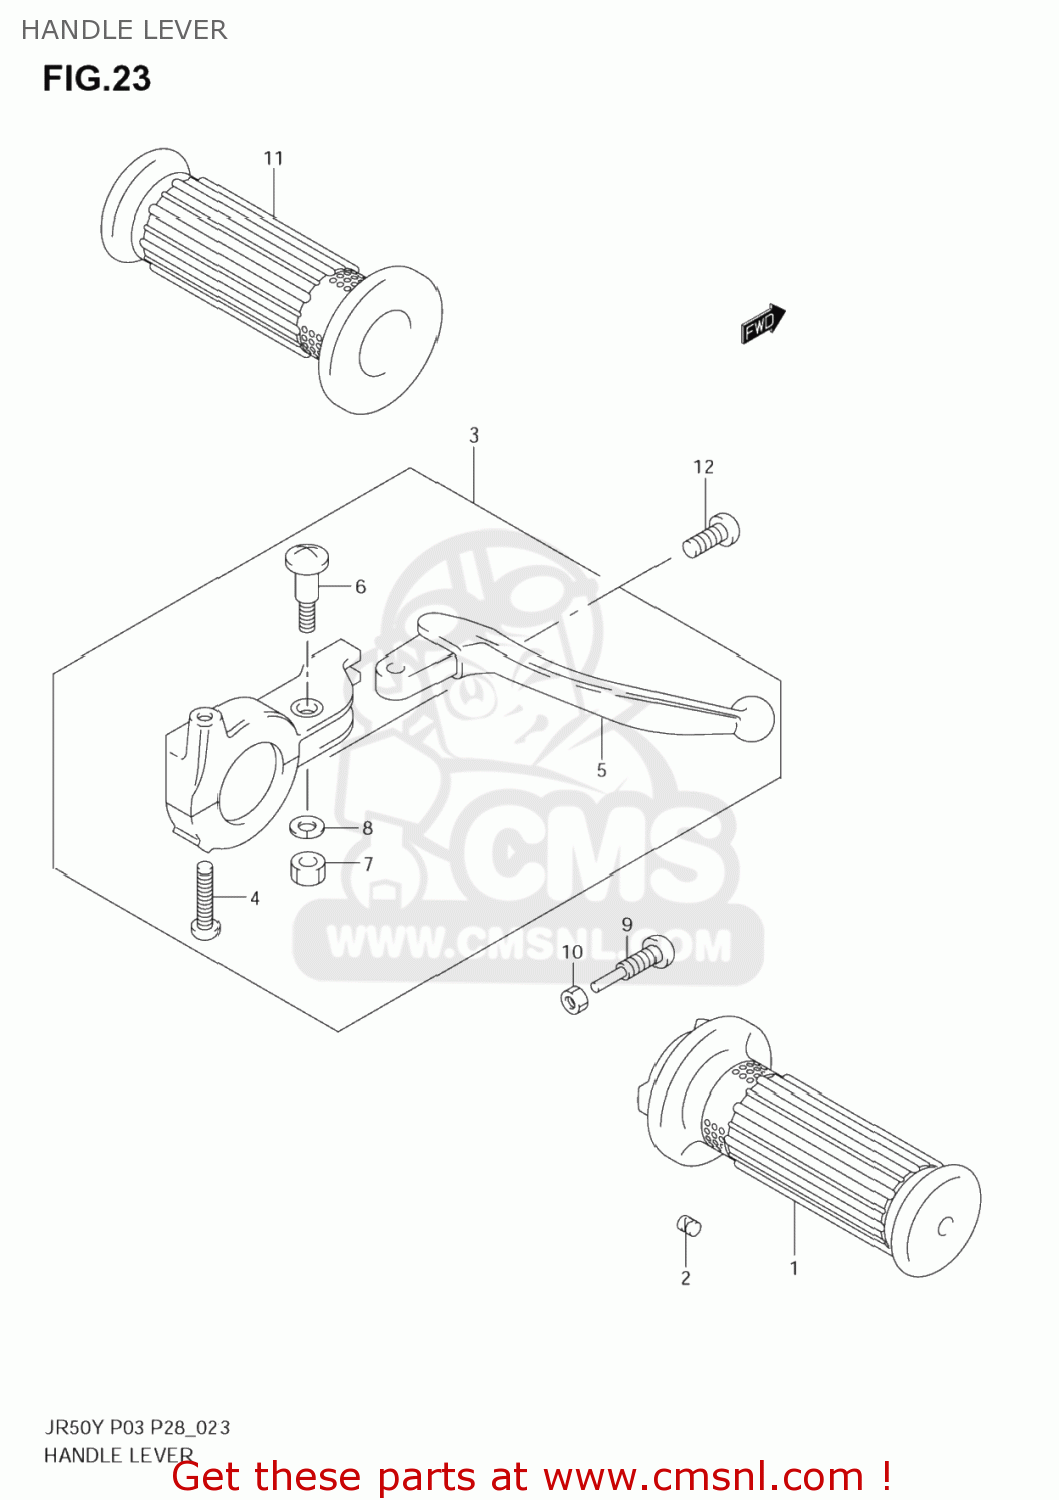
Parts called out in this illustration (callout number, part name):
1	GRIP,THROTTLE
2	PIECE,THROTTLE END
3	LEVER ASSY,BRAKE
4	SCREW(5X22)
5	LEVER,BRAKE
6	SCREW(5X20)
7	NUT
8	LOCK,WASHER
9	SCREW,THROTTLE GRIP ADJUST
10	NUT
11	GRIP,L
12	SCREW (M5X6)
